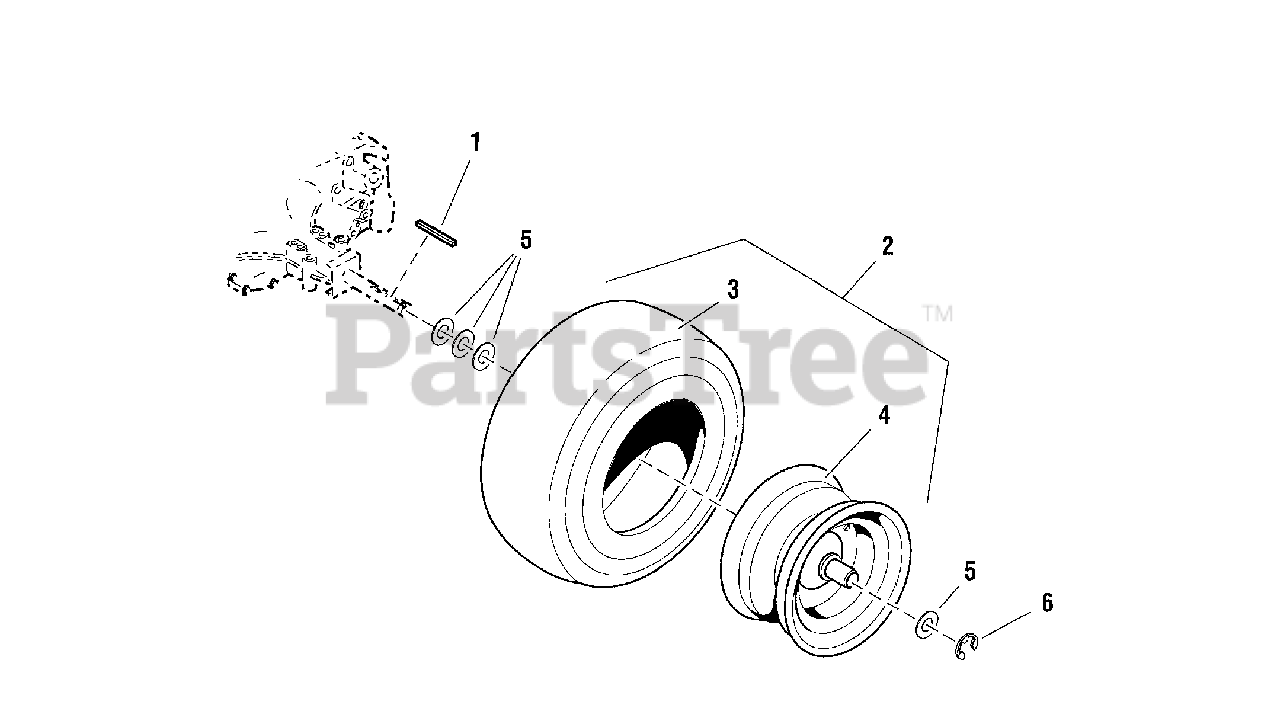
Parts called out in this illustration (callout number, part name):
2	WHEEL & TIRE ASSEMBLY, 16 x 6.5 x 8, Complete (Includes Ref. No. 3 & 4)
3	TIRE, 16. x 6.5 x 8
4	WHEEL ASSEMBLY, 8 x 5.38
